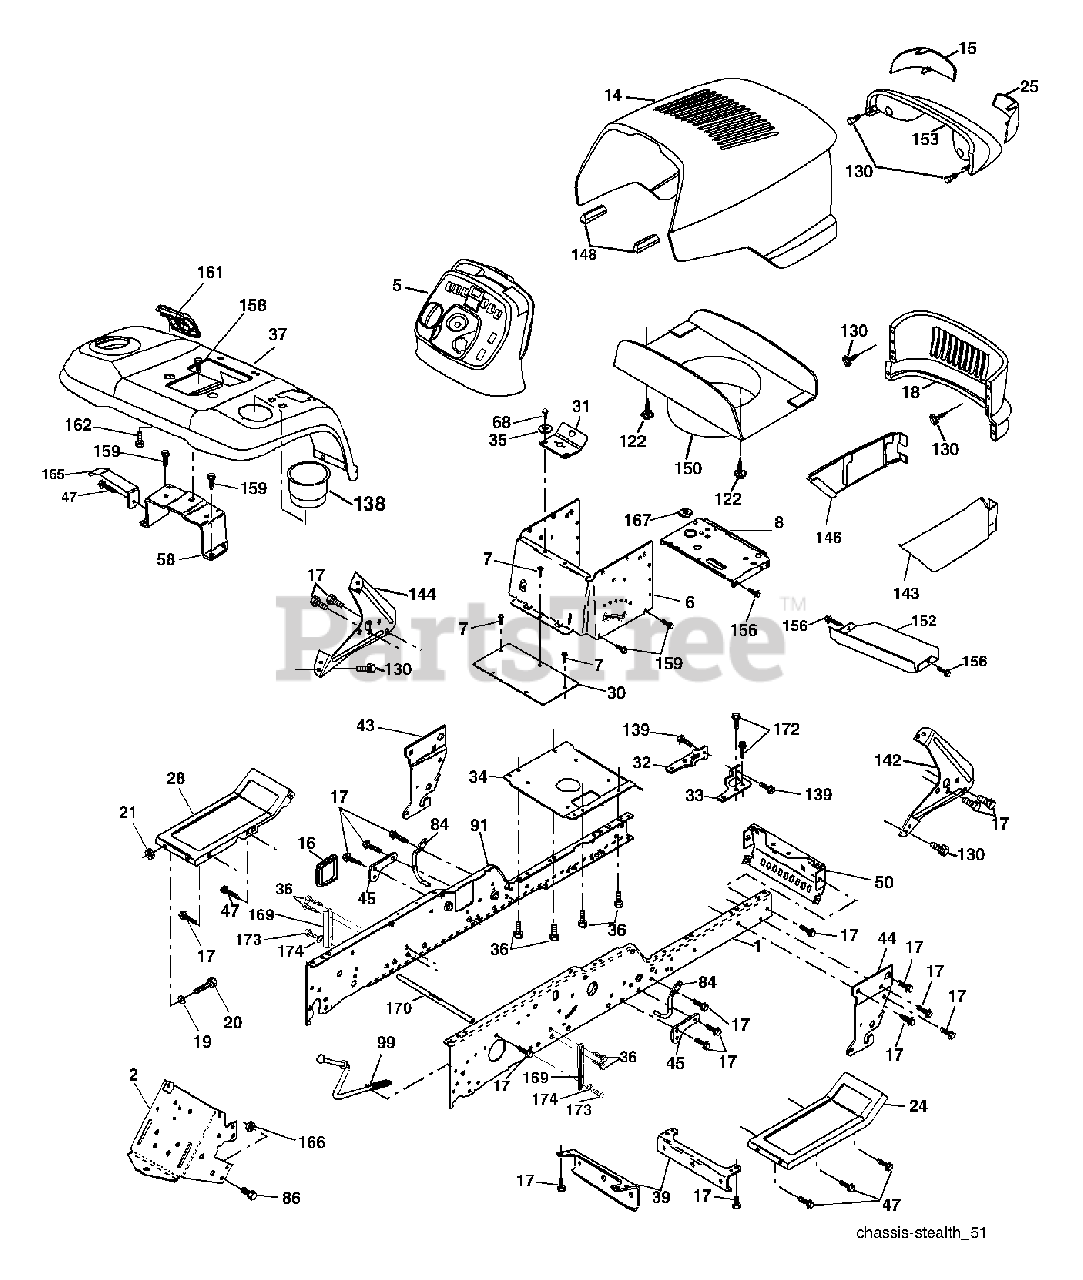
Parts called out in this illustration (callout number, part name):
1	Rail, Kit RH
2	Drawbar, Gt
5	Dash
6	Dash, 1PCS, Lower
7	Screw, Thd Cut 1/4-20 x 1/2
8	Support, Battery
14	Hood Asm., Pnt
15	Lens LH
16	Cover, Access
17	Screw, 3/8-16 x 3/4
19	Washer 13/32 x 13/16 x 12 Ga.
20	Bolt, Fin Hex 3/8-16 x 1
21	Nut, Crownlock 3/8-16
24	Footrest, RH
25	Lens RH
28	Footrest, LH
31	Bracket Supt 1-pc Vgt Steering
32	Bracket, Frame Pivot Lh
33	Bracket, Frame Pivot Rh
34	Plate Asm Engine Chassis
35	Washer 11/32 x 11/16 x 16 Ga.
36	Screw 5/16-18 x 3/4
37	Fender, Pnt.
39	Bracket, Axle Front
43	Bracket, Spnsn Front Lh
44	Bracket, Spnsn Front Rh
45	Bracket, Susp Arm
47	Screw Thdrol 3/8-16 x 1/2
50	Bracket, Chassis Front
56	Bracket Asm., Susp Chassis Lh
58	Bracket Asm., Fender
68	Screw, 5/16-18 x 1/2
84	Upstop 54"
86	Bolt, Fin Hex 7/16-14 unc
91	Rail, Kit Lh
99	Rod Asm. Bypass
122	Screw Hex WSHD 8-18 x 7/8
130	Screw 10 x 3/4 Single Lead-Hex
138	Cupholder
139	Bolt Shoulder 5/16-18
142	Bracket Dash Stealth RH
143	Skirt Grille RH
144	Bracket Dash Stealth LH
146	Skirt Grille LH
148	Extrusion Bumper
150	Duct Heat Hood
152	Shield, Browning
153	Lightbox Asm.
156	Screw 5/16-18 x 3/4
158	Screw 3/8-16 x 1/2
159	Screw Hexwsh Thdr. 3/8-16 x 3/4
161	Casale Fuel Window
162	Screw 1/4-1/2 Unc
165	Bracket Support Tank
166	Nut, Lock Hex 7/16-14 unc
167	Bushing Snap Nylon 1.250
170	Rod Bracket Sway Bar
172	Screw 3/8-16 x .875
173	Bolt Fin Hex 5/16-18 UNC x 3/4
174	Washer Lock Hvy HLCL Spr. 5/16
